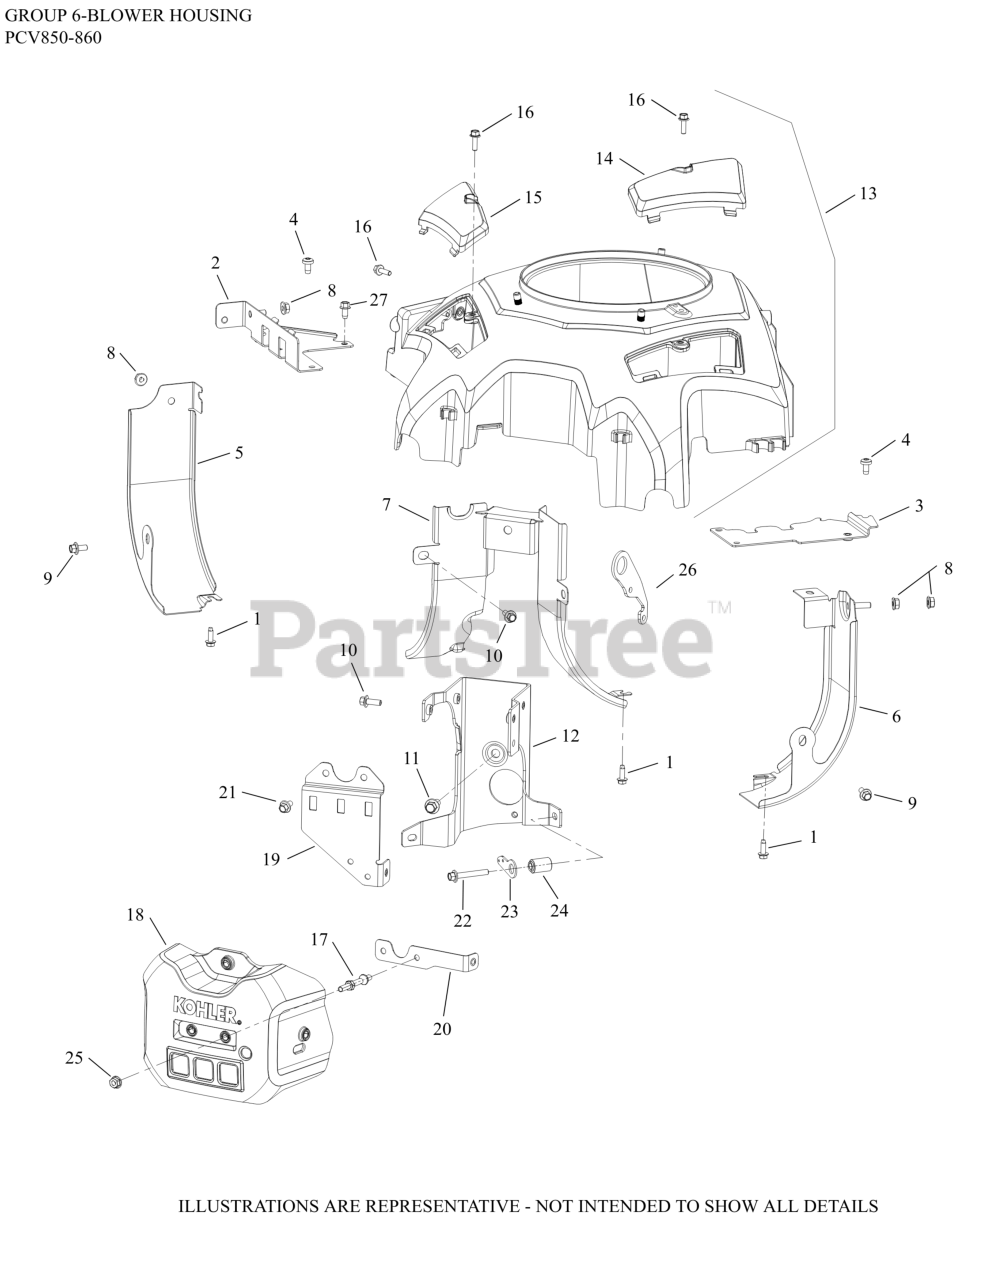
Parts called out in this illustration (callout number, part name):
1	SCREW, THREAD FORMING
2	BAFFLE, CRANKCASE #1 CYLINDER
3	BAFFLE, CRANKCASE #2 CYLINDER
5	BAFFLE, BARREL #1 CYLINDER
6	BAFFLE, BARREL #2 CYLINDER
7	BAFFLE, VALLEY ASSEMBLY
9	SCREW, FLG M6X1.0X12
10	SCREW, FLG M6X1.0X16
11	SCREW, FLG 8X1.25X16
12	BRACKET, THROTTLE BODY
13	KIT, BLOWER HOUSING
14	COVER, CLEAN OUT #2 CYLINDER
15	COVER, CLEAN OUT #1 CYLINDER
16	SCREW, HVY FLG M5X.8X16
19	BRACKET, FUSE HOLDER
21	SCREW, FLG M6X1.0X10
22	SCREW, FLG M6X1.0X40
23	LEVER, GOVERNOR LINKAGE
24	SPACER, STEPPED O.D.
25	NUT, HEX FLANGE
NI	LEVER, GOVERNOR LINKAGE
NI	SCREW,THREAD FORMING
